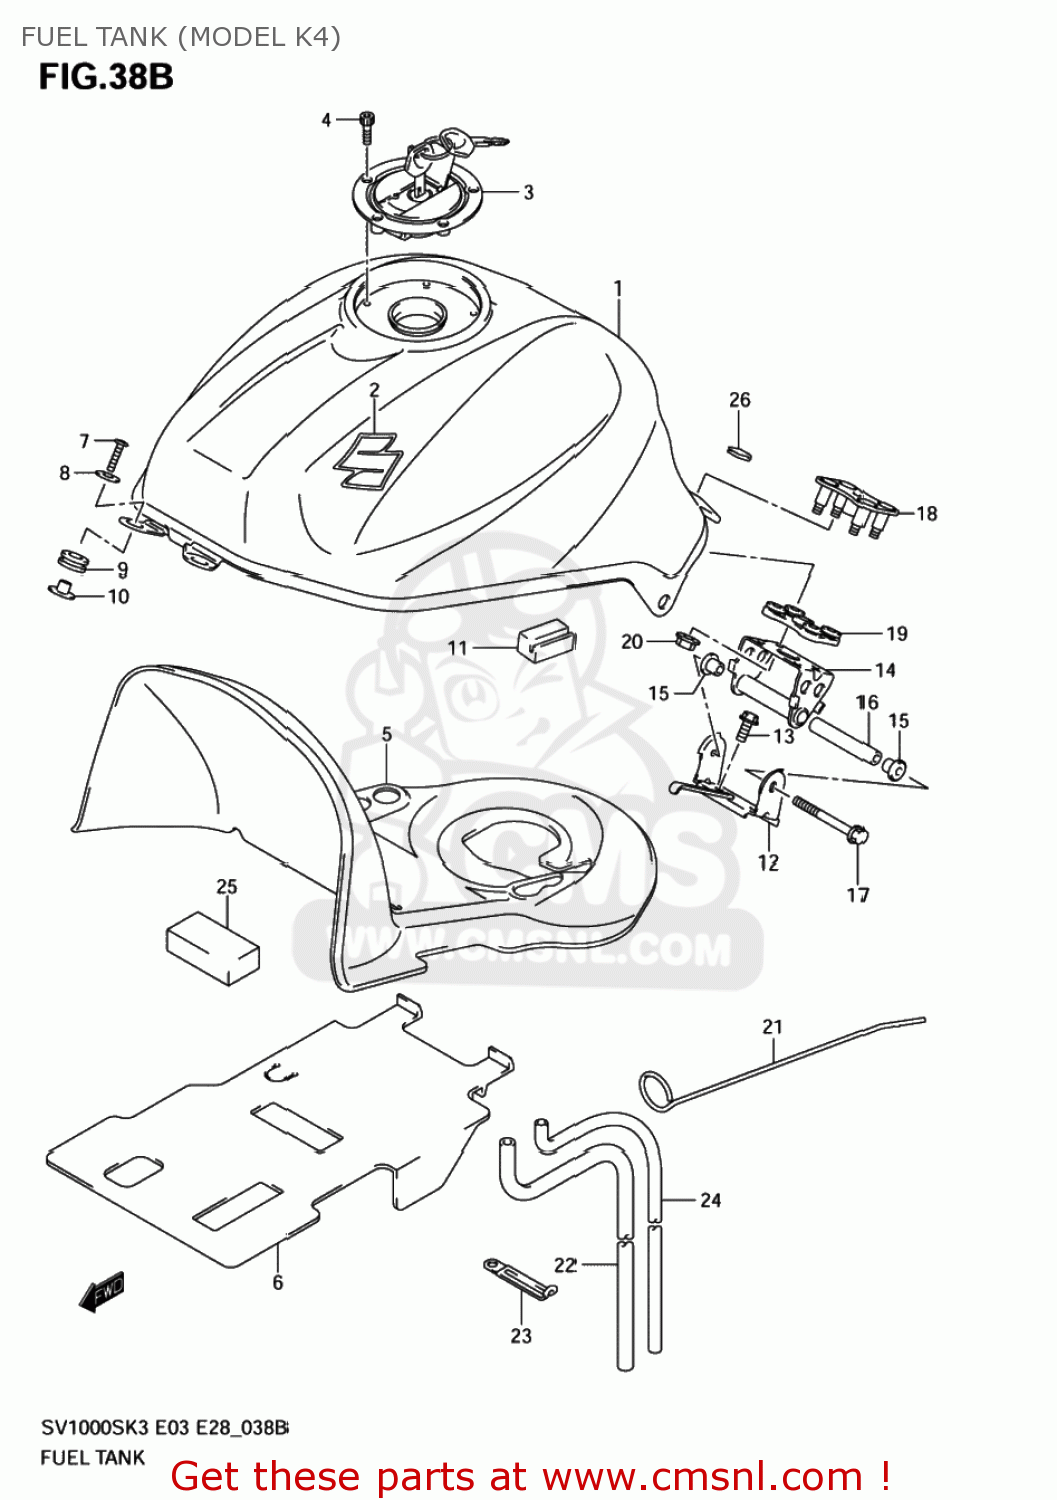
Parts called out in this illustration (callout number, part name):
1	TANK ASSY,FUEL(RED)
2	EMBLEM,"S"(YD8
3	CAP SET,FUEL TANK
4	BOLT(5X20)
5	SHIELD,FUEL TANK HEAT
6	SHEET,HEAT SHIELD RUBBER
7	SCREW(6X25)
8	WASHER(6.5X22X1.6)
9	CUSHION,FUEL TANK FR
10	SPACER,FUEL TANK FR
11	CUSHION,FUEL TANK SIDE
12	BRACKET,FUEL T
13	BOLT
14	BRACKET,FUEL TANK NO.1
15	CUSHION,TANK RR BRACKET
16	SPACER,FUEL TANK RR
17	BOLT(6X100)
18	BRACKET,FUEL TANK RR UP
19	CUSHION,FUEL TANK RR
20	NUT
21	STAY,FUEL TANK
22	HOSE,WATER DRAIN
23	CLAMP(L:80)
24	HOSE,FUEL TANK
25	CUSHION,FUEL TANK
26	MOLDING
